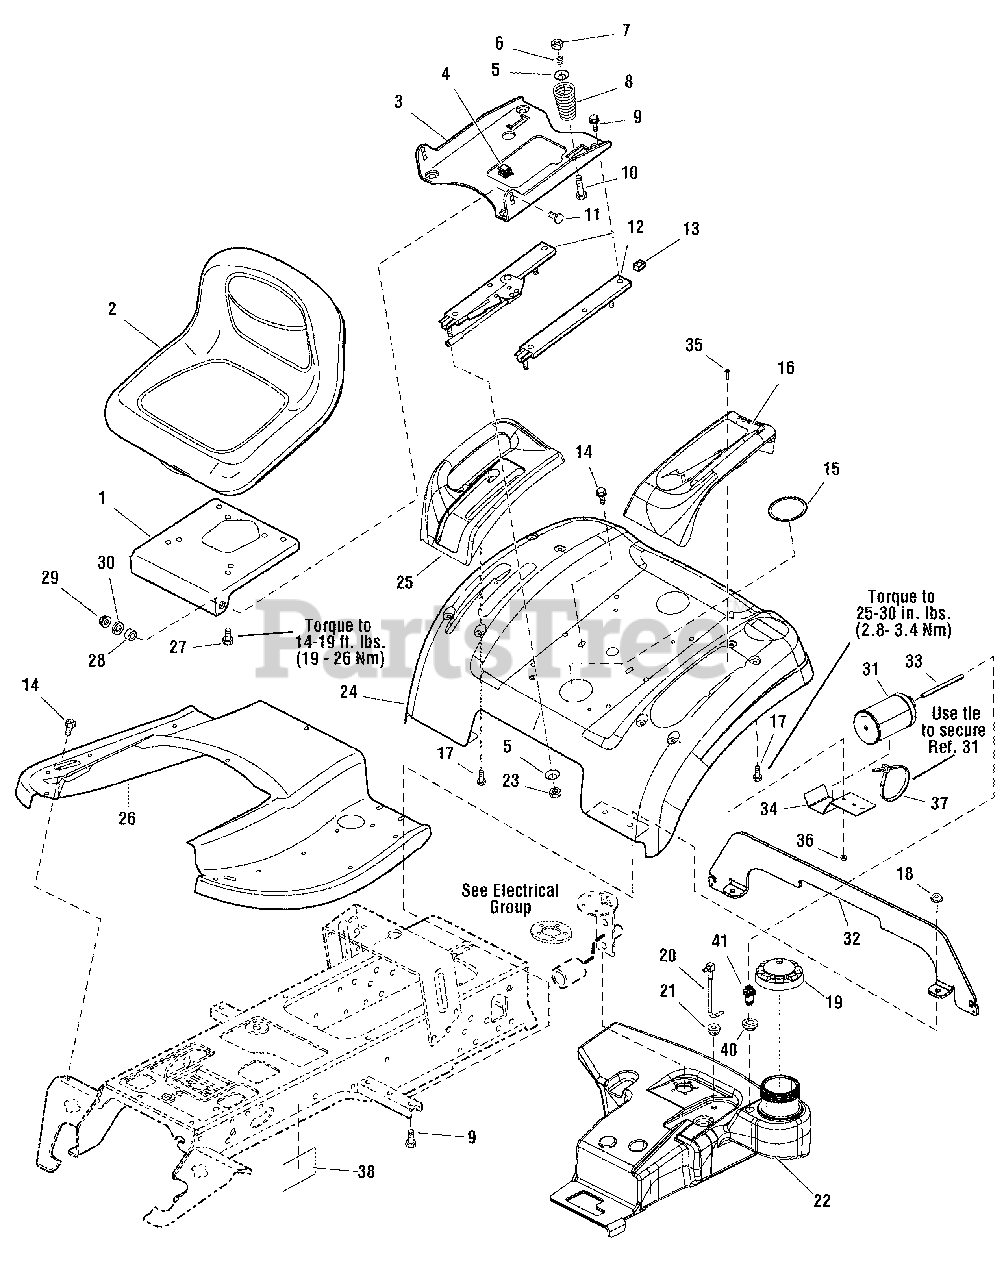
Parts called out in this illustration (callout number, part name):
1	BRACKET, 1-5/8 x 1-3/4
2	SEAT, 18"
3	SUPPORT, Seat
4	CLIP, Wire
5	WASHER, Spring, 5/16 x 1-1/4
6	SPRING, Compression
7	NUT, Hex Lock, ESNA Light, 5/16-18
8	SPRING, Compression
9	CAPSCREW, Hex Flange Whiz Lock, 5/16-18 x 3/4
10	BOLT, Carriage, 5/16-18 x 2
11	BOLT, Carriage, 3/8-16 x 1
12	SLIDE, Seat
13	NUT, Speed, 5/16-18, Lug Type
14	CAPSCREW, Hex Washer Head Taptite, 5/16-18 x 5/8
15	PLUG, Plastic
16	POD, with Cup Holder, LH
17	CAPSCREW, Hex Washer Head, 1/4-20 x 5/8
18	NUT, Hex Flange Whiz Lock, 5/16-18
19	CAP, Gas
20	TUBE & ELBOW ASSEMBLY
21	BUSHING, 3/8 x 9/16 x 5/8, Rubber
22	TANK, Fuel
23	NUT, Hex KEPS, 5/16-18
24	DECK, Seat, Orange
24	DECK, Seat, Red
25	POD, RH with 2 Slots
26	TUNNEL, Orange
26	TUNNEL, Red
27	CAPSCREW, Hex Flange Whiz Lock, 5/16-18 x 1
28	SPACER, 25/64 x 5/8 x 3/16, Hardened
29	NUT, Hex Flange Two-Way Lock, 3/8-16
30	WASHER, 3/8
31	CARBON CANISTER, 300CC
32	SUPPORT, Mower Hanger
33	HOSE, Vapor
34	BRACKET, Canister Mounting
35	SCREW, Round Head Phillips, #10-24 x 3/4
36	NUT, KEPS Lock, #10-24
37	TIE, Self Locking
38	DECAL, EVAP, Viper
38	DECAL, EVAP, LSI Viper
40	GROMMET
41	REMOTE VENT ASSEMBLY
